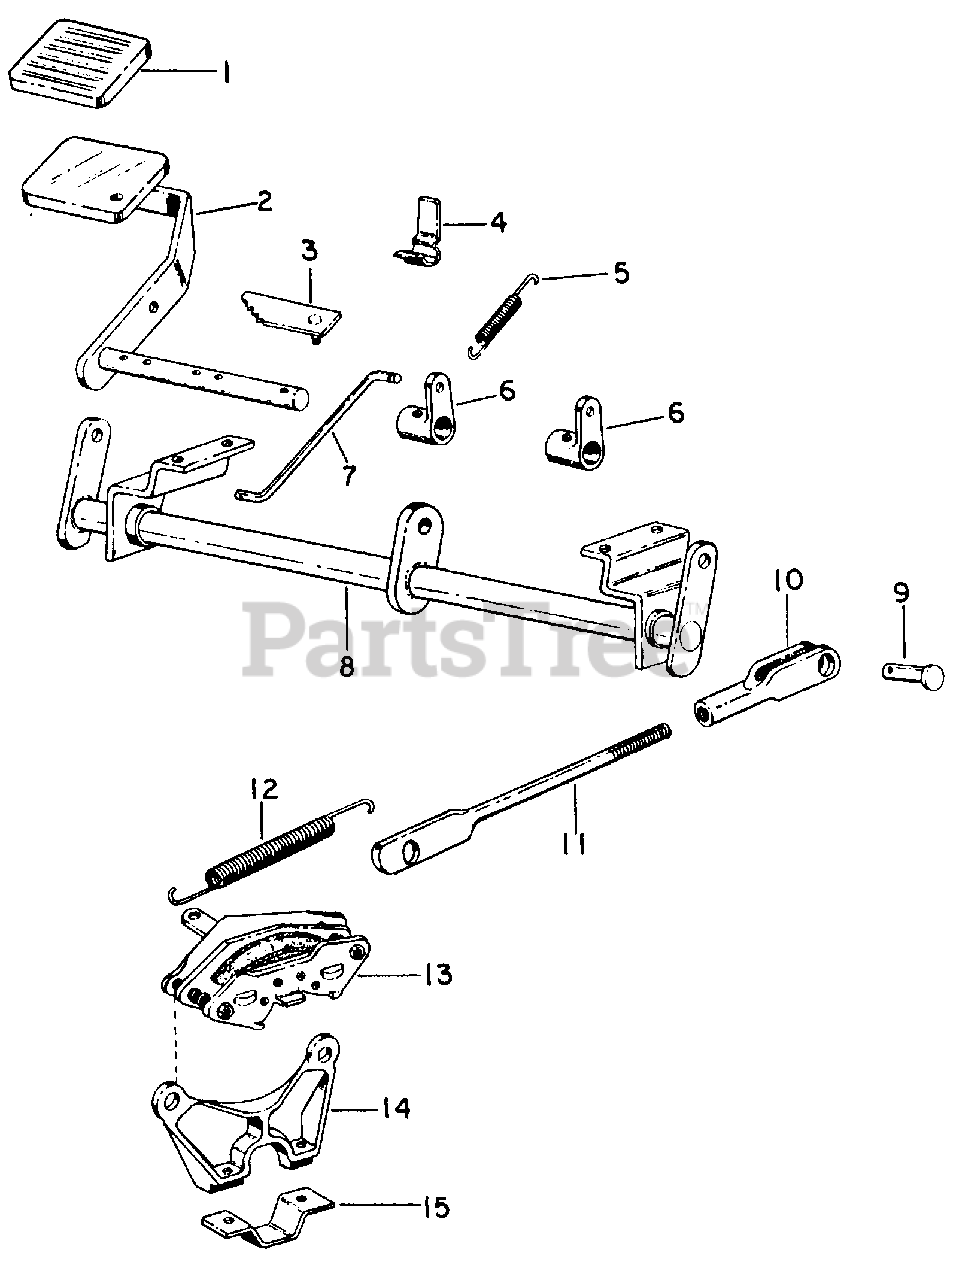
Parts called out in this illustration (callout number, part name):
1	Pad, Pedal
2	Pedal Assy, Brake
3	Ratchet, Brake Lock
4	Spring, Switch Operating
5	Spring, Return
8	Shaft Assy, Brake
9	Pin, 3/8 X 1.060 Clevis
10	Clevis, 3/8-24 X 2-1/2 C-Z Lt Adj
11	Rod, Brake
12	Spring, Brake
13	Caliper Assy, Brake
14	Bracket, Brake Mounting
15	Flange, Caliper Mounting
